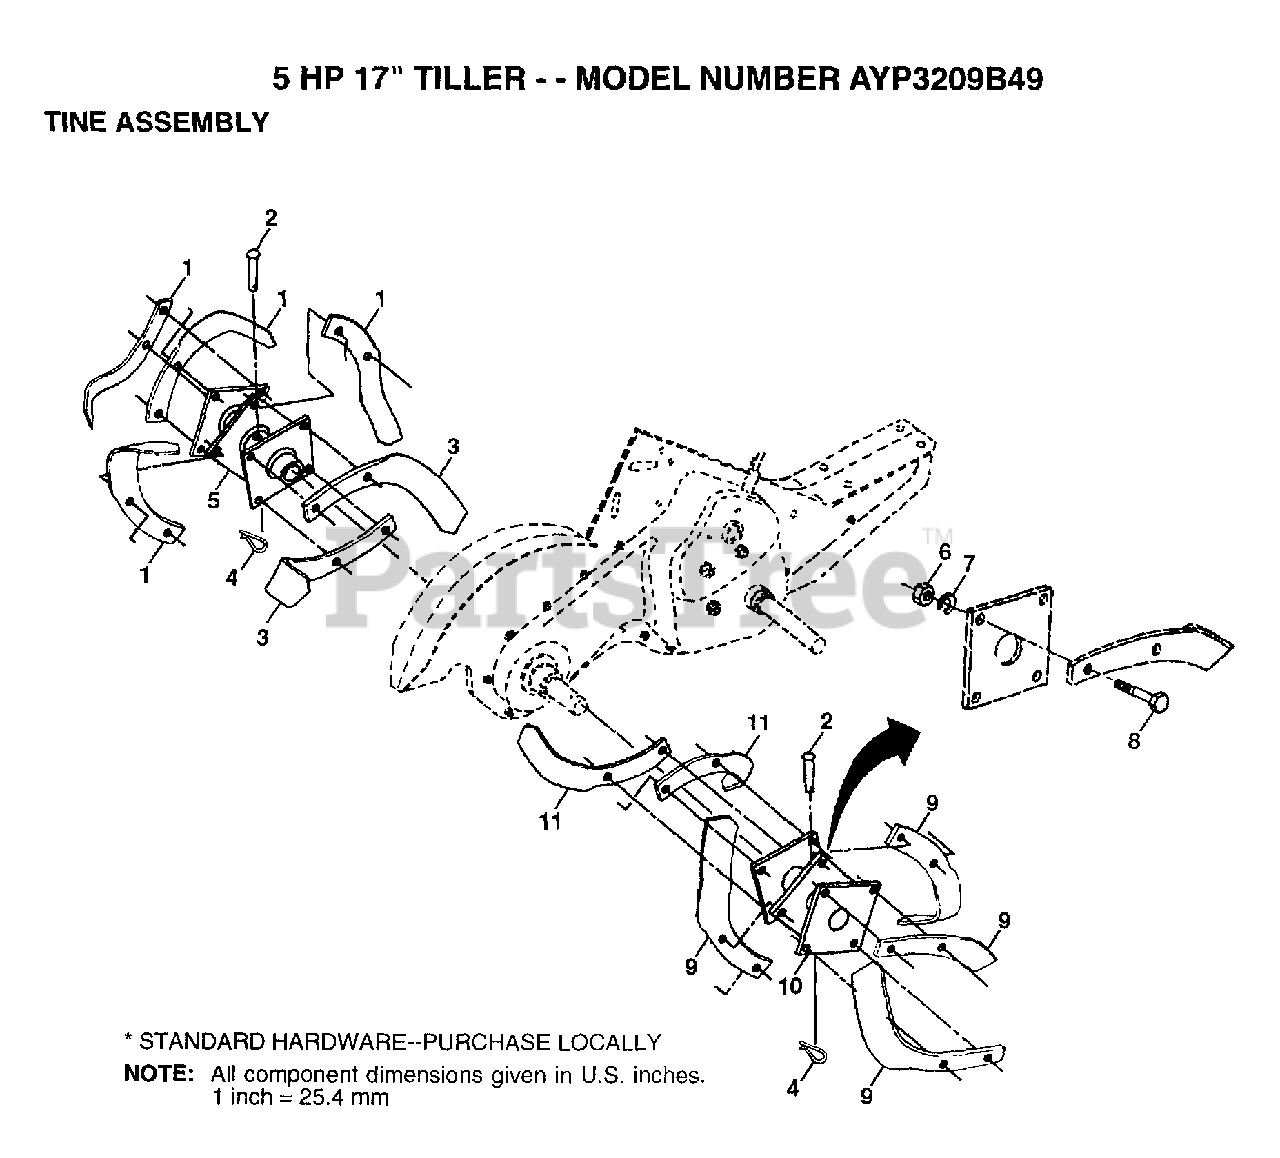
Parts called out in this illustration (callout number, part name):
2	PIN.CLEVIS.SHEAR
3	"TINE.LH.12"""
4	RETAINER.SPRING
5	HUB&PLATE ASM LH
7	LOCKWASHER
8	BOLT
10	ASSY HUB AND PLATE RH
11	"TINE.RH.12"""
